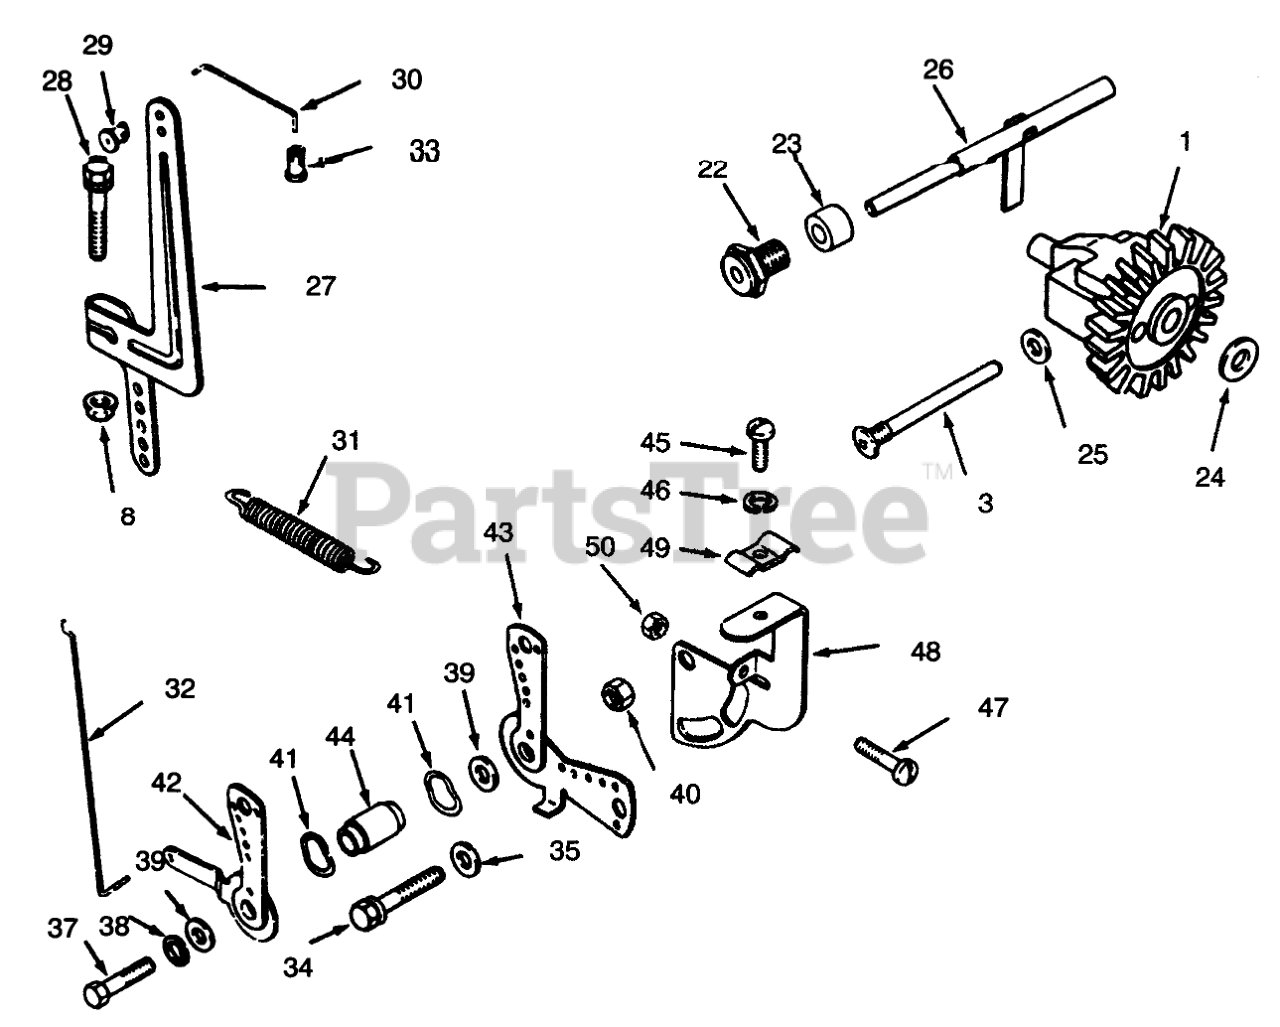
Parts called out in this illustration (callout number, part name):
1	Kit-Governor Gear (Includes 24)
3	Govenor Stop Pin
8	Palnut
22	Bushing
23	Spacer
24	Washer
25	Washer
26	Kit-Governor Cross Shaft
27	Governor Lever
28	Screw
29	Bushing
30	Carburetor Linkage
31	Spring (Governor to Cab.)
32	Choke Linkage (Carb. to Choke Shaft)
33	Bushing
34	Screw
35	Washer
37	Screw
38	Washer-Lock
39	Washer
41	Washer
42	Choke Control Lever
43	Lever-Throttle Control
44	Space
45	Screw
46	Washer
47	Screw
48	Bracket-Clutch Control
49	Clamp
